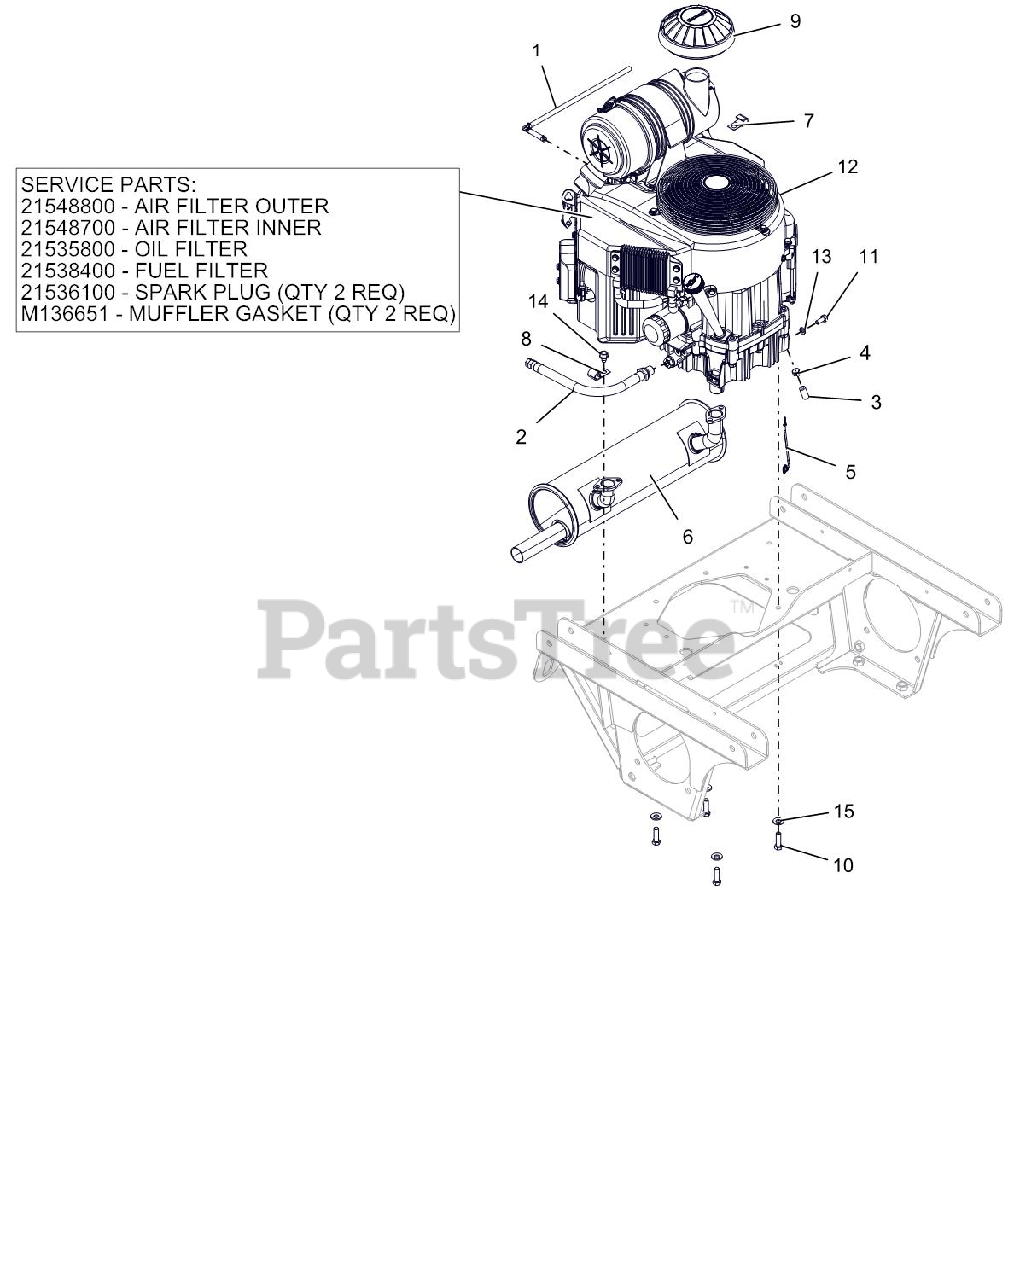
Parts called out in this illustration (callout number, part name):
1	ASM, VAPOR LINE
2	HOSE, OIL DRAIN
3	HOSE, .25 LOW-PERM BULK GAS
4	CLAMP, FUEL LINE
5	LEAD - STARTER SOLENOID
6	MUFFLER, 27-31 KAW
9	CAP, AIR CLEANER INTAKE (2")
10	BLT-HEX.38-16X1.25 G5YZ NYTORQ
11	@BLT-HEX M8-1.25X20 YWZC
12	FILTER,OIL - KAW
12	PLUG, SPARK
12	FILTER, OUTER
12	FILTER, INNER - KAW
12	ENGINE, KAWASAKI FX850
12	GASKET, MUFFLER #
12	FUEL FILTER - KAWASAKI
13	@WSHR-LK .31X.078 REG YWZC
14	@SCR-TAP .38-16X.50 HWH TR YWZ
15	WASHER, 3/8" SPRING DISC
